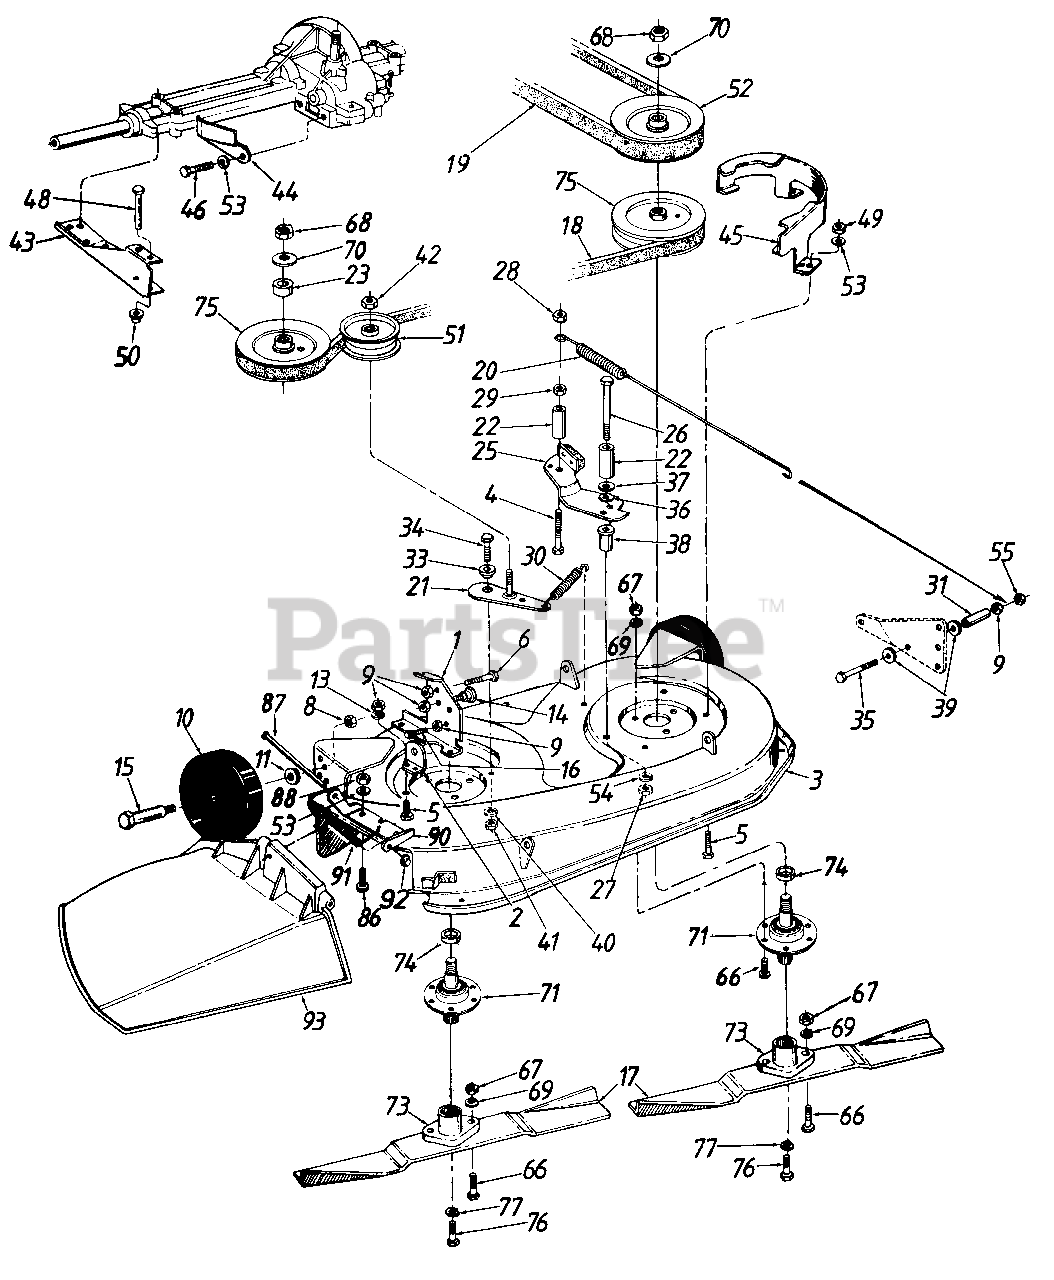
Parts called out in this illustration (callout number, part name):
1	Deck Disengagement Brkt.
2	Rear Deck Brkt.-R.H.
3	32" Deck Ass'y.
4	Hex Bolt 1/4-28 x 1.75" Lg.
5	Hex Bolt 1/4-20 x .62" Lg.*
6	Hex Wash. Hd. Scr. 1/4-20 x 1.5" Lg.
8	Hex L-Nut 3/8-16 Thd.
9	Hex Nut 1/4-20 Thd.
10	Deck Wheel
11	Bell-Wash. .380" I.D. x .88"
13	L-Wash. 1/4" I.D.
14	Shld. Bolt .498" Dia. x .34"
15	Shld. Bolt .498" Dia. x 1.53"
16	Hex Tap Scr. 1/4-20 x .75" Lg.
17	R.H. High-Lift Blade
18	V-Belt
19	V-Belt
20	Extension Spring 15-5/8" Lg.
21	Idler Brkt. Ass'y.
22	Spacer 5/16" I.D. x 1/2" O.D. x 31/32"
23	Spacer .752" I.D. x 1.25" O.D.
25	Deck Brake Brkt. Ass'y.
26	Hex Bolt 5/16-18 x 3.25" Lg.
27	Hex Nut 5/16-24 Thd.
28	Hex L-Nut 1/4-28 Thd.
29	Hex Nut 1/4-28 Thd.
30	Extension Spring 4.35" Lg.
31	Spacer 1/4" I.D. x 3/8" O.D. x 1-5/16"
33	Shoulder Spacer
34	Hex Bolt 3/8-16 x 1" Lg.*
35	Hex Bolt 1/4-20 x 2.5" Lg.
36	Wave Wash. .53" x .78"
37	Shld. Spacer .27" Lg.
38	Spacer 1.46" Lg.
39	Flat Wash. 1/4"
40	L-Wash. 3/8" I.D.*
41	Hex Nut 3/8-16 Thd.
42	Hex L-Nut 3/8-24 Thd.
45	Belt Guard Deck-R.H.
46	Hex Bolt 1/4-20 x .62" Lg.*
48	Pin 2-1/2" Lg.
49	Hex Nut 1/4-20 Thd.*
50	Speed Nut 1/4" Rod
51	Flat Idler Pulley
52	5" Dia. Pulley
53	L-Wash. 1/4" I.D.*
54	Bell-Wash. 5/16" I.D.
55	Hex L-Nut 1/4-20 Thd.
66	Hex Bolt 5/16-24 x 1n Lg.
67	Hex Nut 5/16-24 Thd.*
68	Hex Jam Nut 5/8-18 Thd.
69	L-Wash. 5/16" I.D.*
70	Bell-Wash. 5/8" I.D.
71	Blade Spindle Ass'y. Comp.
73	Blade Adapter
74	Spacer
75	5" Dia. Pulley
76	Hex Bolt 3/8-24 x 1.0 Lg.
77	L-Wash. 3/8" I.D. H.D.
86	Truss.-Mach. Scr. 1/4-20 x .75" Lg.
87	Hinge Pin
88	Hex Nut 1/4-20 Thd.*
90	Hinge Mtg. Brkt.
91	Torsion Spring
92	Push Nut
93	Chute Ass'y. Comp.
